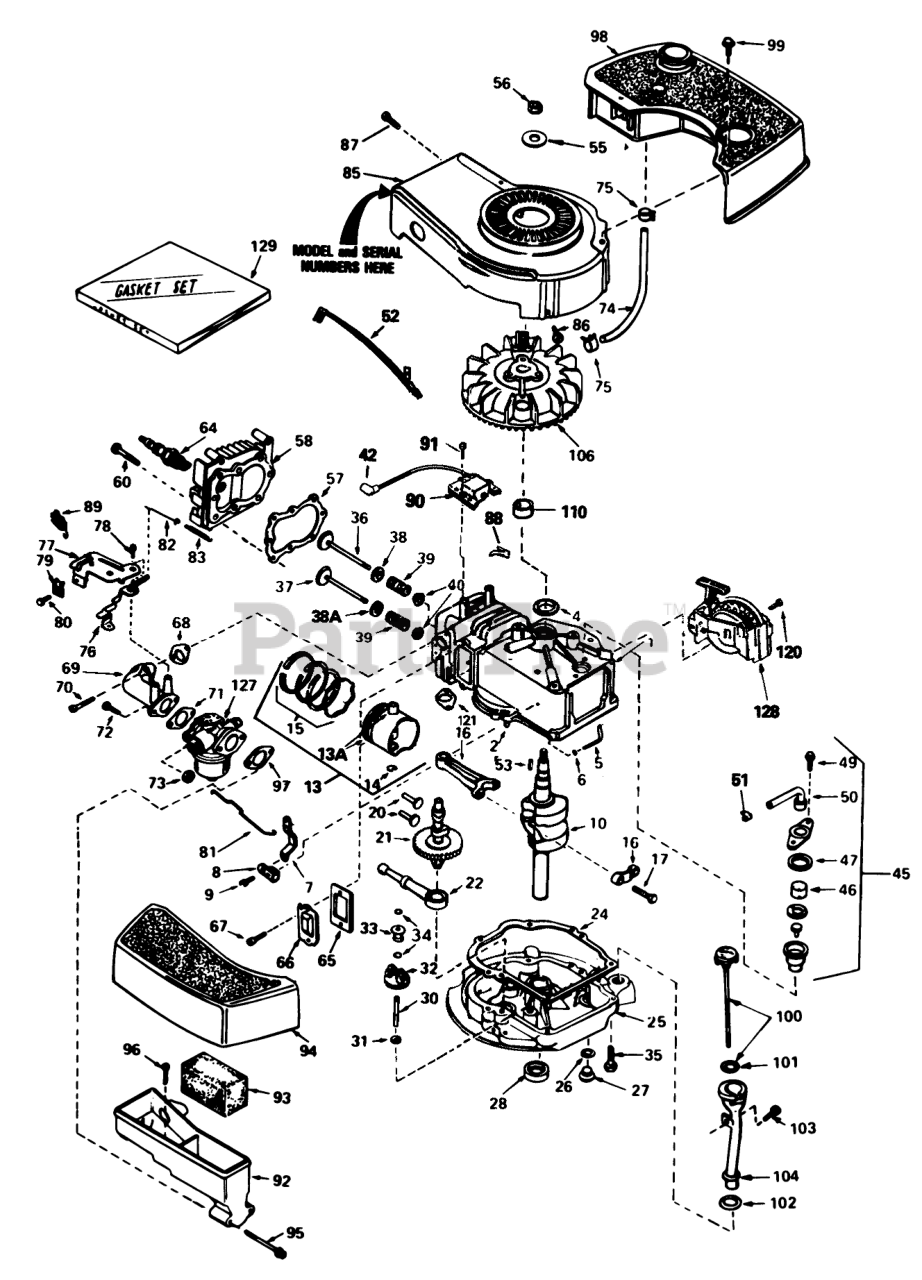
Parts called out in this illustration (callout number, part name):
1	Cylinder Assembly (Incl. Ref. #2 & 4)
2	Pin-Dowel
4	Seal-Oil
5	Rod-Governor (Incl. Ref. #6)
6	Washer-Flat
7	Governor Lever
8	Clamp-Lever, Governor
9	Screw
10	Crankshaft
13	Piston-Pin & Ring Assy. (Std.) (Incl. Ref. #13A, 14 & 15)
13	Piston-Pin & Ring Assembly (.010 oversize) (Incl. Ref. #13A, 14 & 15)
13	Piston-Pin & Ring Assembly (.020 oversize) (Incl. Ref. #13A, 14 & 15)
13A	Piston & Pin Assembly (Std.) (Incl. Ref. #14)
13A	Piston & Pin Assembly (.010 oversize) (Incl. Ref. #14)
13A	Piston & Pin Assembly (.020 oversize) (Incl. Ref. #14)
14	Ring-Retaining, Piston Pin
15	Ring Set (Std.)
15	Ring Set (.020" OS)
15	Ring Set (.010" OS)
16	Rod Assembly-Connecting (Incl. Ref. #17)
17	Bolt-Rod, Connecting
20	Lifter-Valve
21	Camshaft(Mech.Comp. Release)
22	Oil Pump ASM
24	Gasket
25	Flange Assembly-Mounting (Incl. Ref. #26, 27, 28 8 30)
26	Gasket-Oil Drain
27	Plug Oil Drain
28	Seal Oil
30	Shaft-Governor
31	Washer-Flat
32	GearAssembly-Governor (Incl. Ref. #31)
33	Spool-Governor
34	Ring-Retaining
35	Screw (1/4-20 x 1-1/4)
36	Valve-Intake (Std.) (Incl. Ref. #40)
36	Valve-Intake (1 /32" oversize) (Incl. Ref. #40)
37	Valve-Exhaust (Std.) (Incl. Ref. #40)
37	Valve-Exhaust (1 /32" oversize) (Incl. Ref. #40)
38	Seal Assy., Intake
38A	Cap-Upper Valve Spring
39	Spring-Valve
40	Cap-Valve, Spring
42	Cover-Spark Plug
45	Breather Assembly (Incl. Ref. #46 thru 51)
46	Element-Breather
47	Gasket-Breather
49	Screw (10-24 x 9/16)
50	Tube, Breaker
51	Clip, Breather
52	Wire-Ground
53	Key-Flywheel
55	Washer-Belleville
56	Nut-Flywheel
57	63573 GIL 42 SNWTHW
58	Head-Cylinder
60	Screw (5/16-18x1-1/2)
64	Spark Plug-Resistor (R J19 L M)
65	Gasket-Breather
66	Cover-Valve
68	Gasket-Intake
69	Pipe-Intake (Incl. Ref. #68)
70	Screw (1/4-20 x 1)
71	Gasket-Carburetor
72	Screw (1/4-28 x 7/8)
73	Nut and Lock Washer (1/4-28)
74	Line-Fuel
75	Clamp-Line, Fuel
76	Lever Control
77	Control Assembly-Speed (Incl. Ref. #76, 78 & 89)
78	Screw, Hex Washer Hd Shoulder Self-Tap
79	Conduit
80	Screw (10-32 x 3/8)
81	Link-Throttle
82	Link Governor Spring
83	Spring Governor
85	Housing-Blower
86	Screw (1/4-20x19/32)
87	Screw (10-24 x 9/16)
88	Clip-Wire
89	Terminal
90	Solid State
91	Screw
92	Body Air Cleaner
93	Filer, Air
94	Cove, Air Cleaner
95	Screw Fil Hd.
96	Screw, Hex Washer Hd Shoulder Self-Tap
97	Gasket-Air Cleaner
98	Tank-Fuel
99	Screw (10-32 x 35/64)
100	Dipstick-Oil (Incl. Ref. #101)
103	Screw (10-32 x 1/2)
104	Tube-Oil Fill
106	Flywheel
120	Screw (1/2-20x5/8)
121	Gasket Exhaust
127	Carburetor (Incl. #71)
128	Starter-Sidemount
129	Gasket Set (Incl. items marked )
